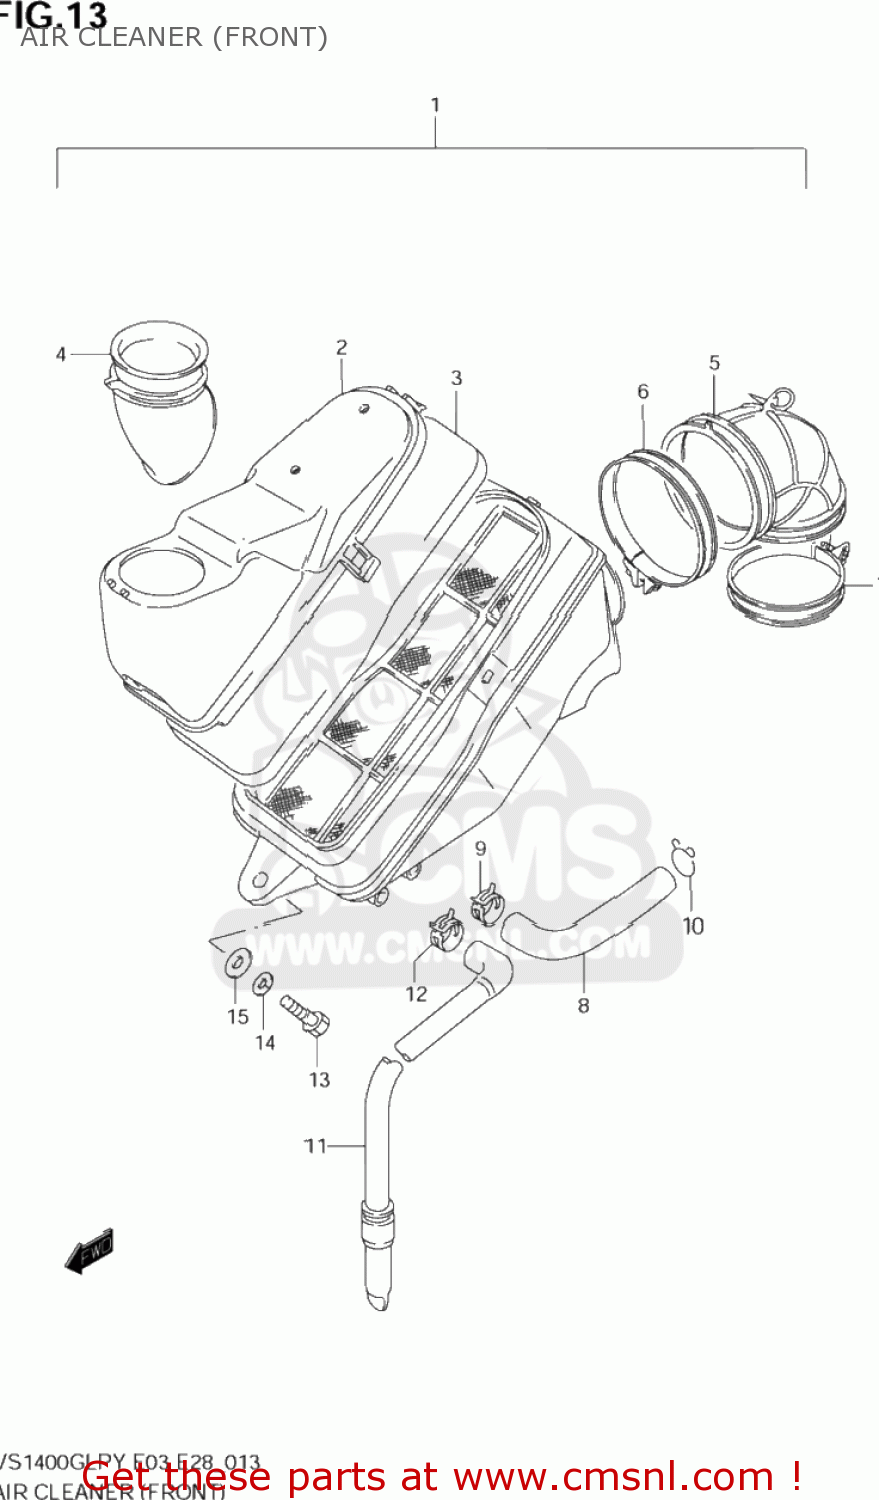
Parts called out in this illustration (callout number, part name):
1	CLEANER ASSY,AIR FR
2	CAP,AIR CLEANER FR
3	FILTER,AIR FR
4	TUBE,INLET
5	TUBE,AIR CLEANER OUTLET
6	CLAMP
7	CLAMP
8	TUBE,BREATHER
9	CLIP
10	CLIP
11	TUBE,DRAIN
12	CLIP
13	BOLT
14	WASHER,LOCK
15	WASHER(6.5X16X1.2)
